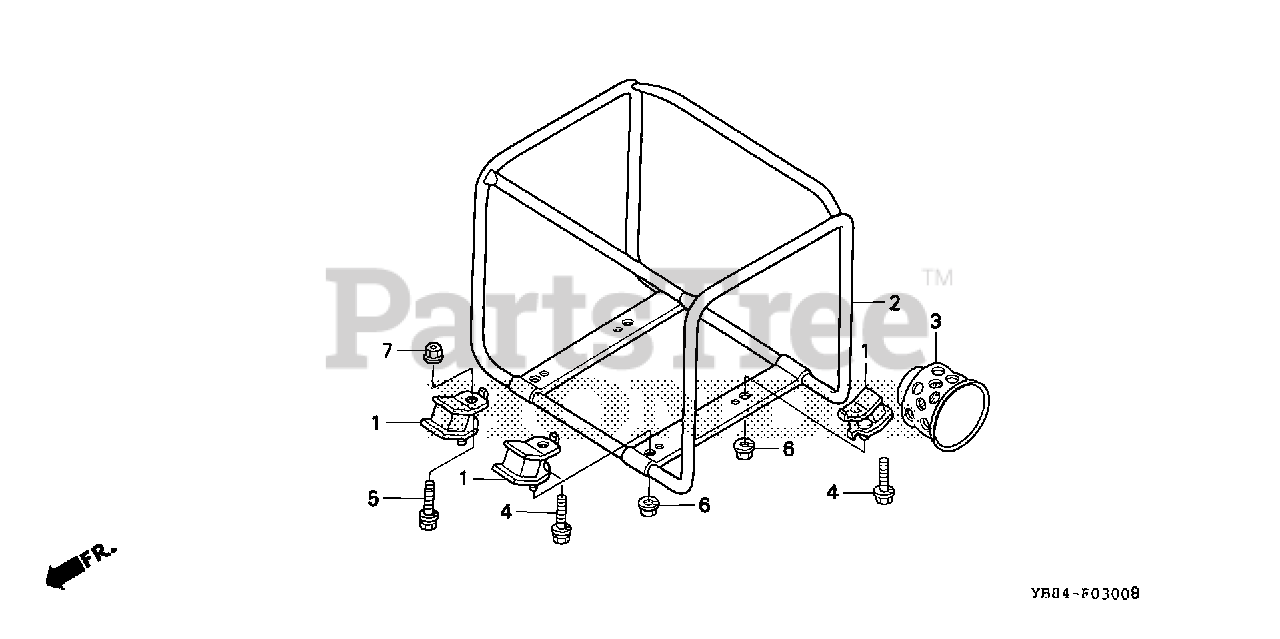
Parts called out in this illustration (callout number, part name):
1	RUBBER (LOWER)
2	FRAME (NOT AVAILABLE)
3	STRAINER
4	BOLT-WASHER (10X25)
5	BOLT-WASHER (10X40)
6	NUT-WASHER (8MM)
7	NUT-WASHER (10MM)
